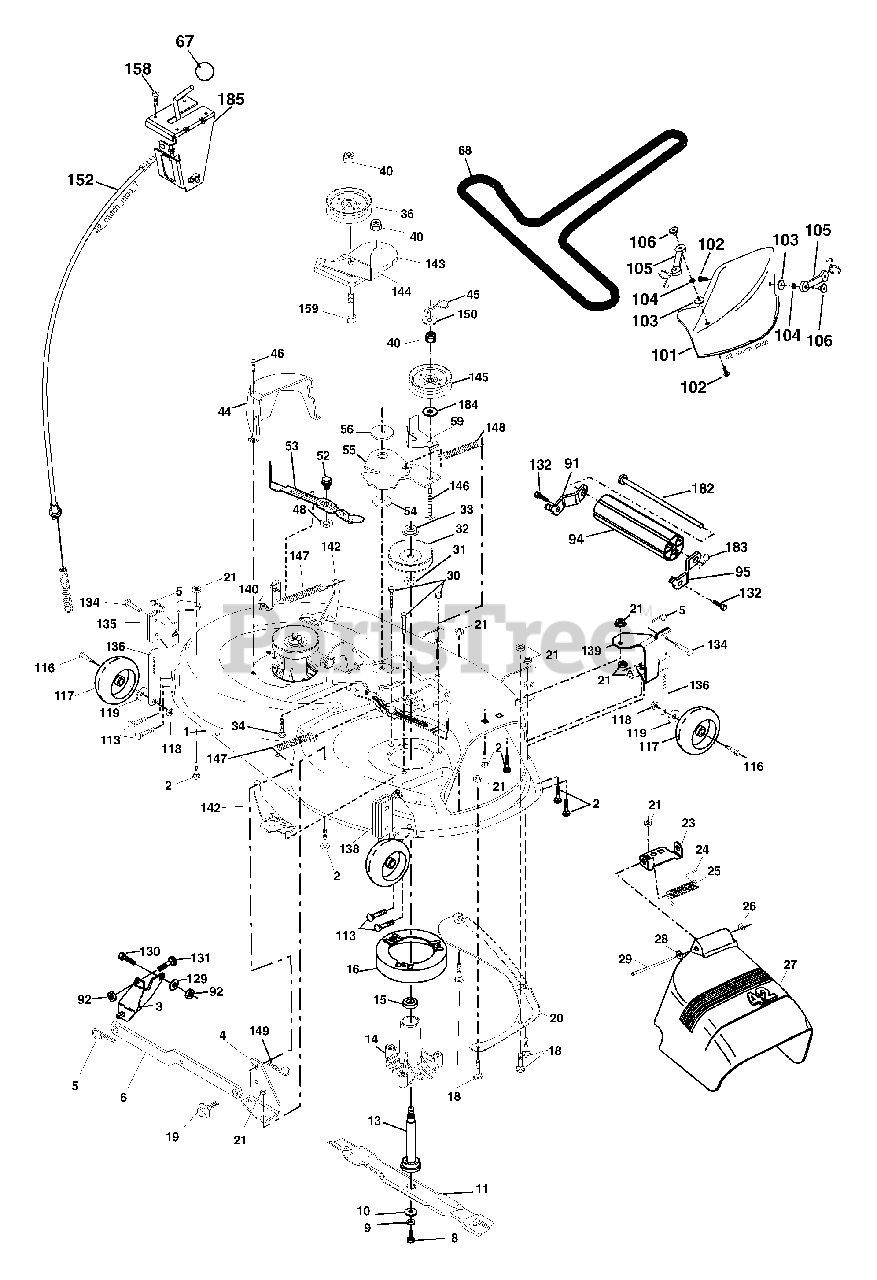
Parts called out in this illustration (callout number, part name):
1	Mower Deck Assembly, 42"
2	Bolt
3	Bracket Asm Fr. Sway Bar 3/42
4	Bracket Asm Deck 42" Sway Bar
5	Retainer Spring
6	Bar Sway Deck
8	Bolt 3/8-24 x 1.25 Gr. 8 patched
9	Washer, Lock
10	Washer, Hardened
11	Blade, Mulching 42" Std
11	Blade Mulching 42" Premium
11	Blade Mower 42" Hi-Lift
13	Shaft Assembly, Mandrel, Vented
14	Housing, Mandrel, Vented
15	Bearing, Ball, Mandrel
16	Stripper, Mandrel Deck
18	Bolt, Carriage 5/16-18 x 5/8
19	Bolt, Shoulder
20	Baffle, Vortex
21	Nut
23	Bracket, Deflector Mower 42"
24	Cap, Sleeve 80 x 112 Blk Mower
25	Spring, Torsion, Deflector 2 52
26	Nut, Push Phos & Oil
27	Shield, Deflector 42" Blk
28	Washer 11/32 x 5/8 x 16 Ga.
29	Rod, Hinge 42" 6 75 W/G
30	Screw Thdrol
31	Washer, Spacer Mower Vented
32	Pulley, Mandrel
33	Nut, Toplock
34	Bolt Carr SH 3/8-16 x 1-1/2 Gr.5
36	Pulley, Idler, Flat
40	Nut Lock 3/8-16
44	Guard, Mandrel, LH
45	Retainer
46	Screw, Thdrol 1/4-20 x 5/8 T
48	Washer, Hardened
52	Bolt, Shoulder 5/16-18 unc
53	Arm Assembly, Pad, Brake
54	Washer, Hardened
55	Arm, Idler
56	Spacer, Retainer
59	Guard TUV Idler
67	Knob
68	V-Belt, 42" Mower
91	Bracket Asm Noseroller LH
92	Nut Lock Hex w/Ins 3/8-16 unc
94	Roller Nose 38 & 42
95	Bracket Asm Noseroller RH
101	Mulcher Cover
102	Screw, Pan Hd Phillip 10-24 x 5/8
103	Washer, Flat
104	Washer, Lock
105	Latch Assembly
106	Nut, Weld
113	Screw 5/16-18 x 3/4
116	Bolt, Shoulder
117	Wheel, Gauge
118	Nut Centerlock 3/8-16
119	Washer 3/8 x 7/8 x 14 Ga.
129	Washer 13/32 x 13/16 x 12 Ga.
130	Bolt Fin HEx 3/8-16 unc x 1 Gr. 5
131	Bolt RDHD SQNK 3/8-16 unc x 1
132	Screw 3/8-16 x .75
134	Pin Head Rivet
135	Bracket Asm. Whl Ga. R LH
136	Bar Adjusting Gauge Wheel
138	Bracket Asm Whl Ga. R RH
139	Bracket Asm. Whl Ga. F RH
140	Bracket Asm Whl Ga. F LH
142	Arm Spring Brake Mower
143	Bracket Arm Idler 42"
144	Keeper Belt 42" Clutch Cable
145	Pulley Idler Flat
146	Bolt Carriage Idler
147	Spring Extension
148	Spring Return Idler
149	Retainer Spring Yellow
150	Washer 9/32 x 3/4 x 10 Ga.
152	Clutch Cable 42"
158	Screw Hex Thd Cut 1/4-20 x 1/2
159	Bolt Rdhd Sqn 3/8-16 unc x 1-3/4
182	Rod Roller Nose
183	Retainer Spring
184	Washer 13/32 x 7/8 x 10 Ga.
185	Head Asm Cable Clutch
